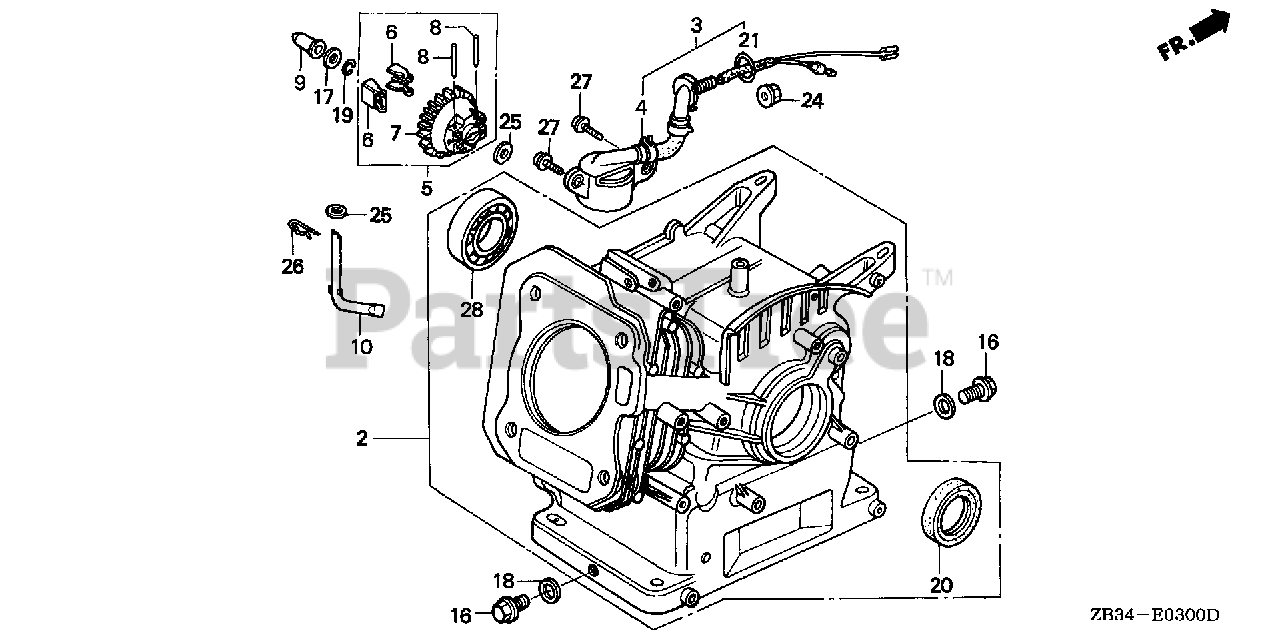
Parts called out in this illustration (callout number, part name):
2	CYLINDER ASSY. (OIL ALERT)
4	SWITCH ASSY., OIL LEVEL
5	GOVERNOR ASSY.
6	WEIGHT, GOVERNOR
7	HOLDER, GOVERNOR WEIGHT
8	PIN, GOVERNOR WEIGHT
9	SLIDER, GOVERNOR
10	SHAFT, GOVERNOR ARM
16	BOLT, DRAIN PLUG
17	WASHER, THRUST (6MM)
18	WASHER, DRAIN PLUG (10.2MM)
19	CLIP, GOVERNOR HOLDER
20	OIL SEAL (25X41X6)
21	O-RING (14MM) (ARAI)
21	O-RING (14MM) (NOK)
24	NUT, FLANGE (10MM)
25	WASHER, PLAIN (6MM)
26	PIN, LOCK (8MM)
27	BOLT, FLANGE (6X12)
28	BEARING, RADIAL BALL (6205TMB) (NTN)
